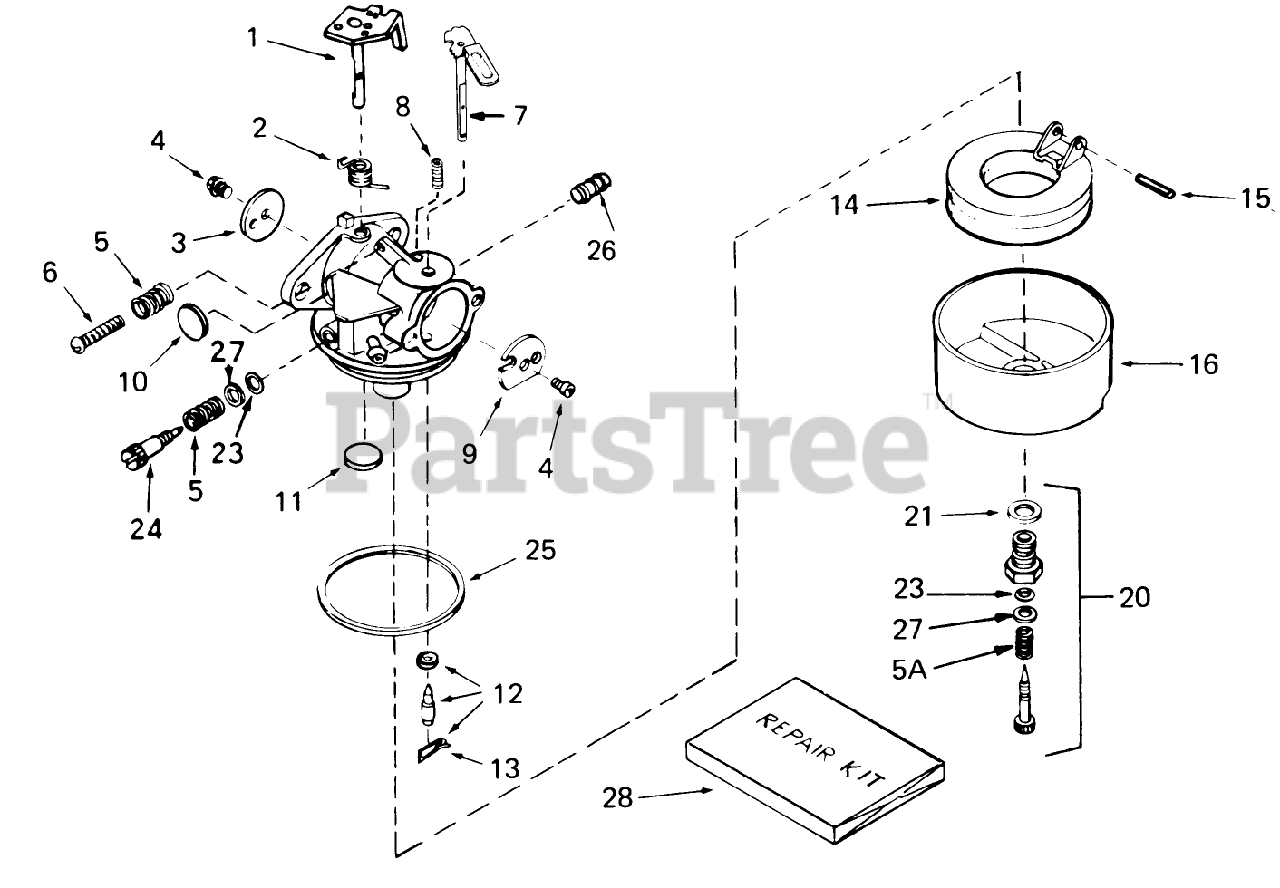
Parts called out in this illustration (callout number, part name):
1	Shaft/Lever-Throttle
2	Spring-Return, Throttle
3	Shutter-Throttle
4	Screw-Shutter
5	Spring-Tension
5A	Spring
6	Screw-Throttle Crack Screw / Idle Speed
7	Choke Shaft and Lever ASM
8	Spring-Positioning, Choke
9	Shutter-Choke
10	Plug-Welch, Idle Mixture Well
11	Plug-Welch, Atmospheric Vent
12	Inlet Needle, Seat Clip Assy. (Incl. No. 13)
13	Clip-Spring
14	Float
15	Shaft-Float
16	Bowl-Float (no drain)
20	Adjustment Screw Assy.,Main (Incl. Ref. #5A,21,23 30)
21	Washer-Bowl Nut
23	ORing
24	Screw Main Adjustment
25	O Ring-Bowl, Float
26	Fitting-Fuel
27	Washer
28	Repair Kit
